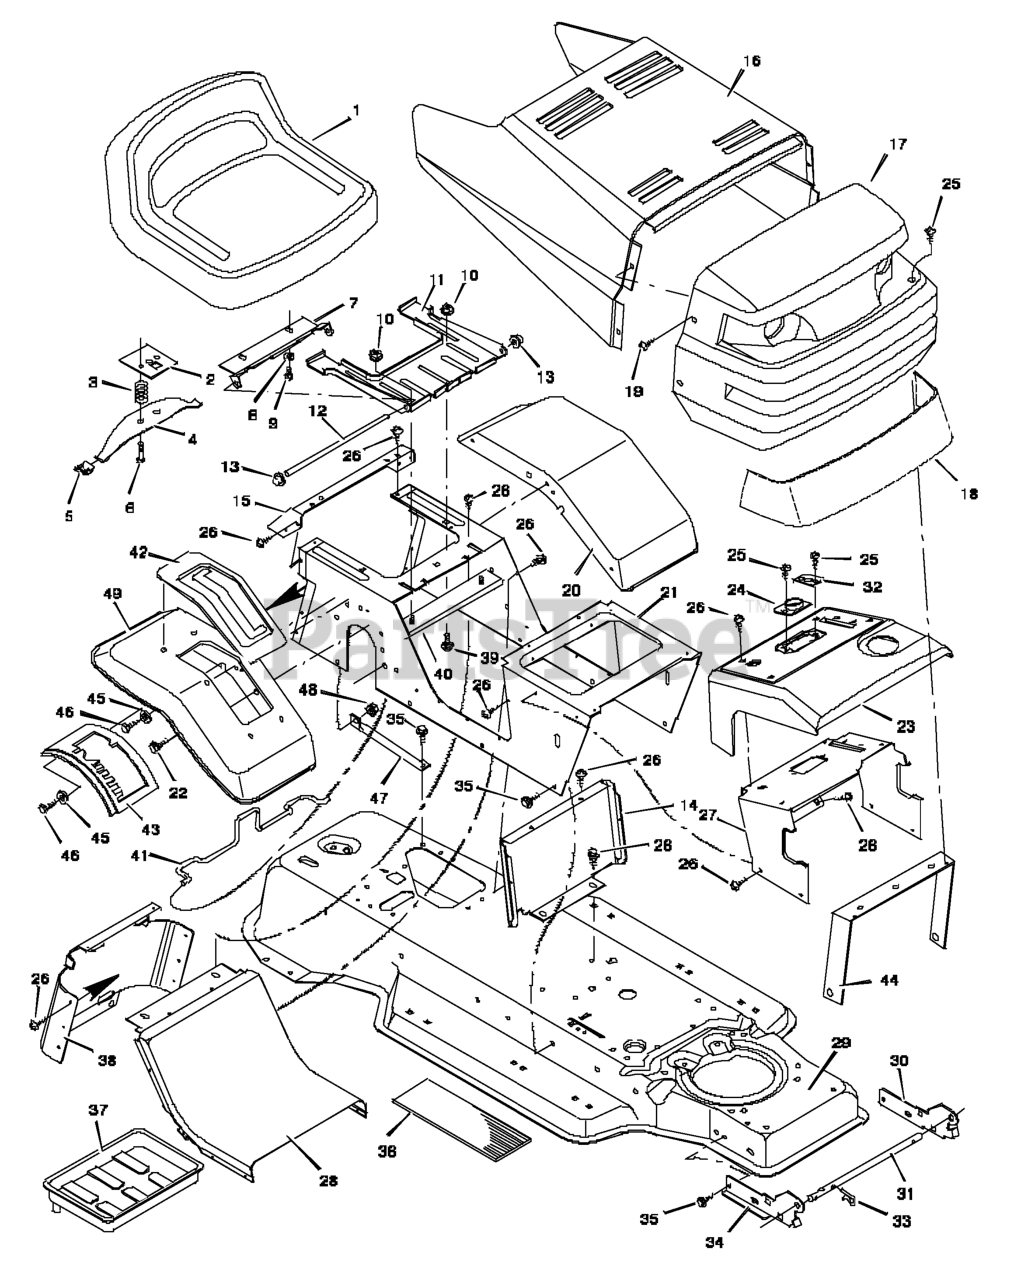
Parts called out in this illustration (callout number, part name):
2	Plate Assembly, Switch
3	Spring, Compression
4	Spring, Seat
5	Glide, Spring
6	Bolt, Shoulder
7	Support, Seat
8	Lockwasher
9	Bolt, Hex
10	Locknut, Flange
11	Bracket, Pivot
12	Rod, Pivot
13	Cap, Push On
14	Insert, Front
15	Fender, Apron
17	Grille Assembly
21	Console Assembly
23	Dash Panel
24	Bearing, Steering
26	Screw
27	Support, Dash
28	Insert, Rear
29	Frame Assembly
30	Bracket, Left Grille
31	Rod, Pivot
32	Bearing
33	Pin, Hair
34	Bracket, Right Grille
37	Tray, Battery
38	Cap, Console
39	Bolt
40	Channel Assembly
41	Clamp, Battery
42	Cover, Shift
43	Gate, Shift
44	Brace, Grille
45	Washer
46	Bolt, Hex
47	Strut, Shifter
48	Locknut
49	Fender, SOG
